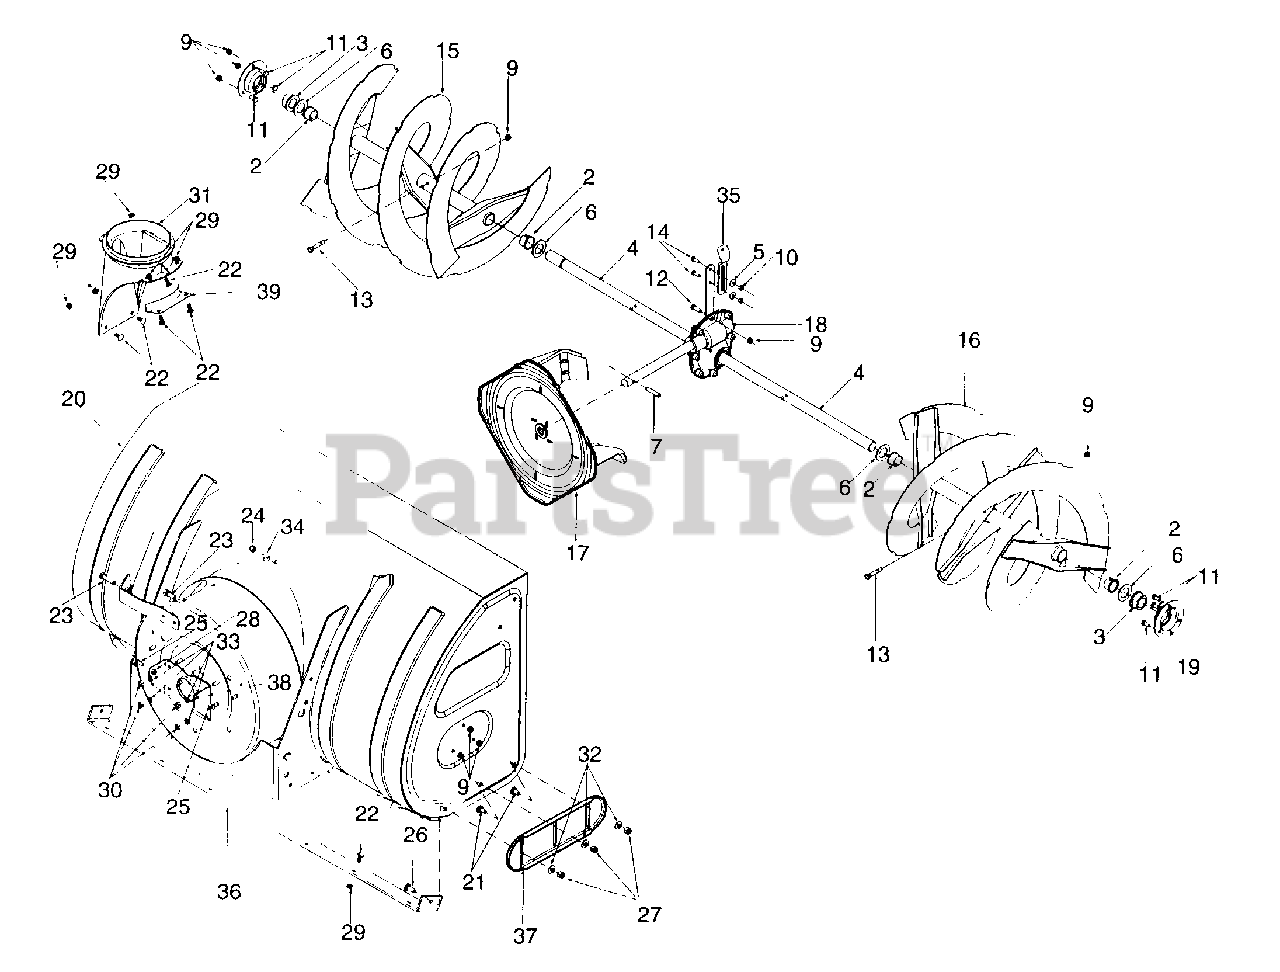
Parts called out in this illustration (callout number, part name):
2	BUSH:FLG:1.05 ID X 1.16 OD
3	BRG: FLG:W/FLATS
4	SPIRAL AXLE 1.00 X 44.12
5	WASH:BELL:.265 X.75 X .062
6	FL-WASH 1.00 ID X 1.75 OD X .1
7	SPRING PIN SPIR 5/16 DIA X 1.7
9	NUT:HX:5/16-18:GRC:LOCK
10	NUT:1/4-28:GRA:HX
11	HHCS:5/16-18: .625:GR5:STD
12	HHCS:5/16-18: .75:GR5:STD
13	SHEAR BOLT 5/16 - 18 X 1-3/4
14	HHCS:1/4-28: .75:GR5:STD
18	GEAR ASM:AUGER
22	BOLT:CAR:5/16-18:.75
23	HHCS:3/8-16:1.50:GR5:STD
24	SCR:AB:5/16-12:0.750:HXINDWSH
25	HHCS:1/4-20:.75:GR5:STD
26	BOLT:CARR:3/8-16
27	NUT:HX:3/8-16:GRC:LOCK
28	NUT:HX:1/4-20:GRC:LOCK
29	NUT: HX: 5/1 6-1 8: GRC: LOCK
30	NUT:5/16-18:GRB:HX
31	CHUT:ADAP:6" DIA
32	WASH:SPR:.401 X .870 X .063
33	WASH:LOCK:5/16:REGULAR DUTY
34	WASH:BELVL:.340 ID X .872 OD
